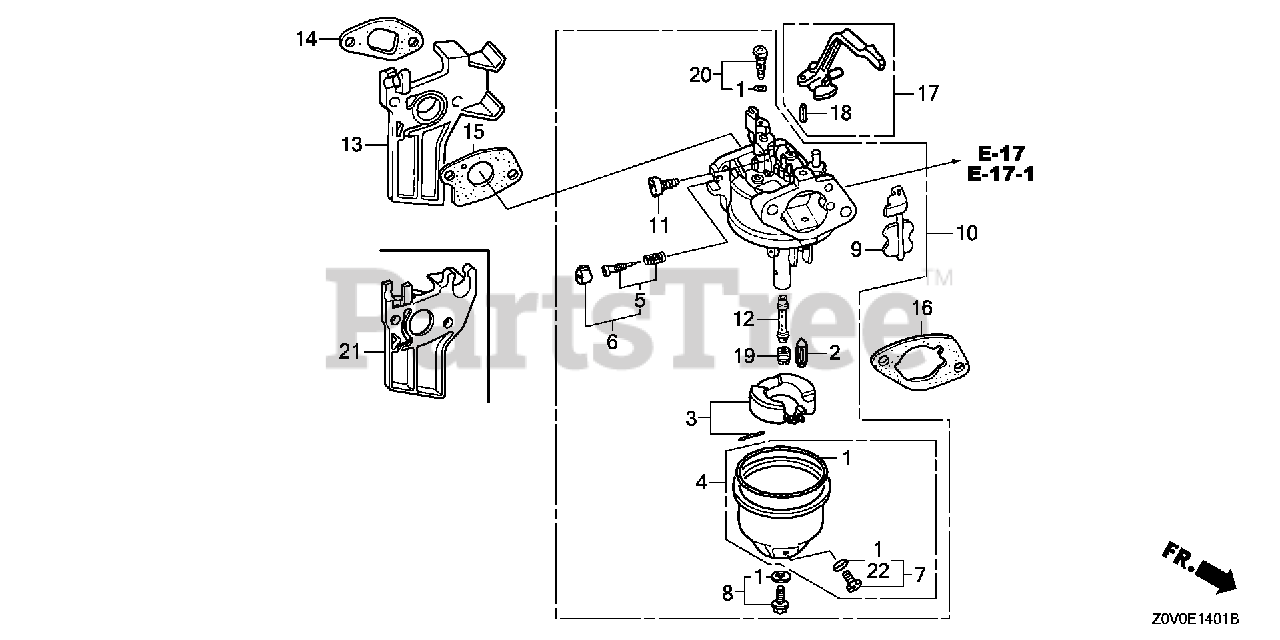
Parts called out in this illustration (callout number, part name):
1	GASKET SET
2	VALVE SET, FLOAT (SEAT NOT INCLUDED)
4	CHAMBER SET, FLOAT
6	SCREW SET, PILOT (CARBURETOR NO.)
7	SCREW SET, DRAIN
8	SCREW SET
10	CARBURETOR ASSY. (BE74J A)
11	SCREW, THROTTLE STOP
12	NOZZLE, MAIN
13	INSULATOR, CARBURETOR
14	GASKET, INSULATOR
15	GASKET, CARBURETOR
16	GASKET, AIR CLEANER
17	LEVER, CHOKE
18	PIN, SPRING (2X12)
19	JET, MAIN (#72)
19	JET, MAIN (#75)
19	JET, MAIN (#78)
20	JET SET, PILOT (#40)
